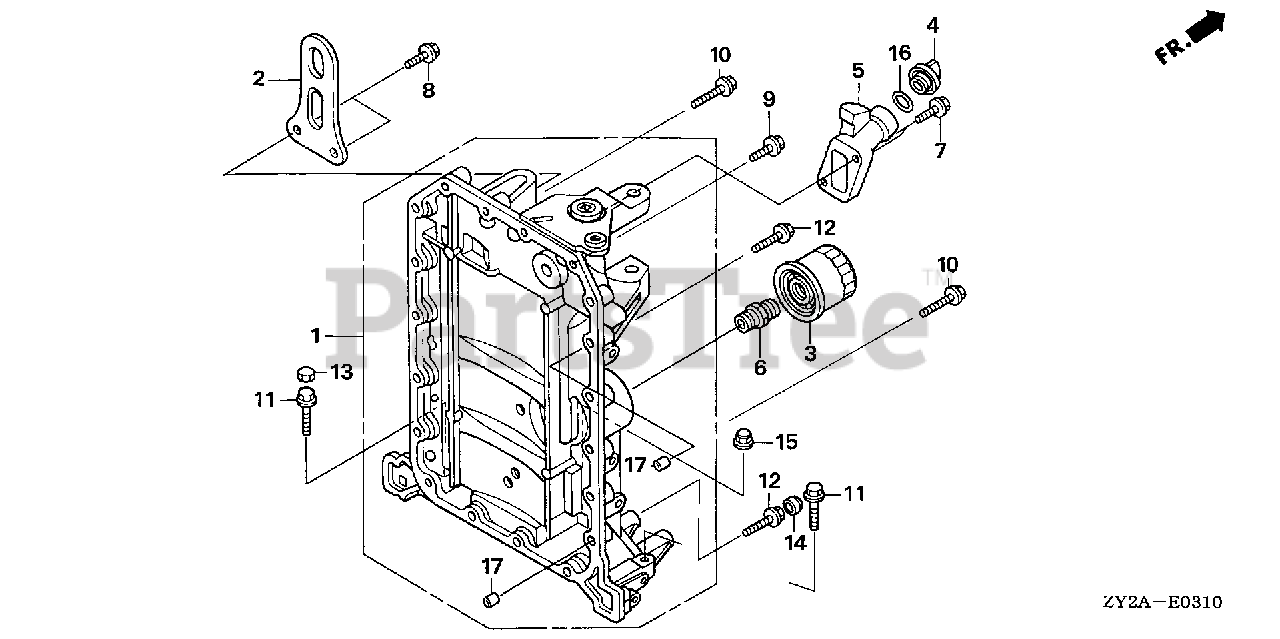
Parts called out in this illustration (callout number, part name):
2	HANGER, ENGINE
3	FILTER, OIL (FILTECH TOYO ROKI) (SOLD INDIVIDUALLY)
3	FILTER, OIL (TOYO ROKI) (SOLD INDIVIDUALLY)
3	FILTER, OIL (FILTECH TOYO ROKI) (SOLD IN MULTIPLES OF 30)
4	CAP, OIL (YELLOW)
5	EXTENSION, OIL FILLER
6	HOLDER, OIL FILTER
7	BOLT, FLANGE (6X22)
8	BOLT, FLANGE (8X20)
9	BOLT, FLANGE (6X32)
10	BOLT, FLANGE (6X55)
11	BOLT, FLANGE (10X55)
12	BOLT, FLANGE (6X37)
13	CAP, BOLT (10MM)
14	CAP, BOLT (6MM)
15	NUT, FLANGE CAP (10MM)
16	O-RING (26X2.7)
17	PIN, DOWEL (8X14)
